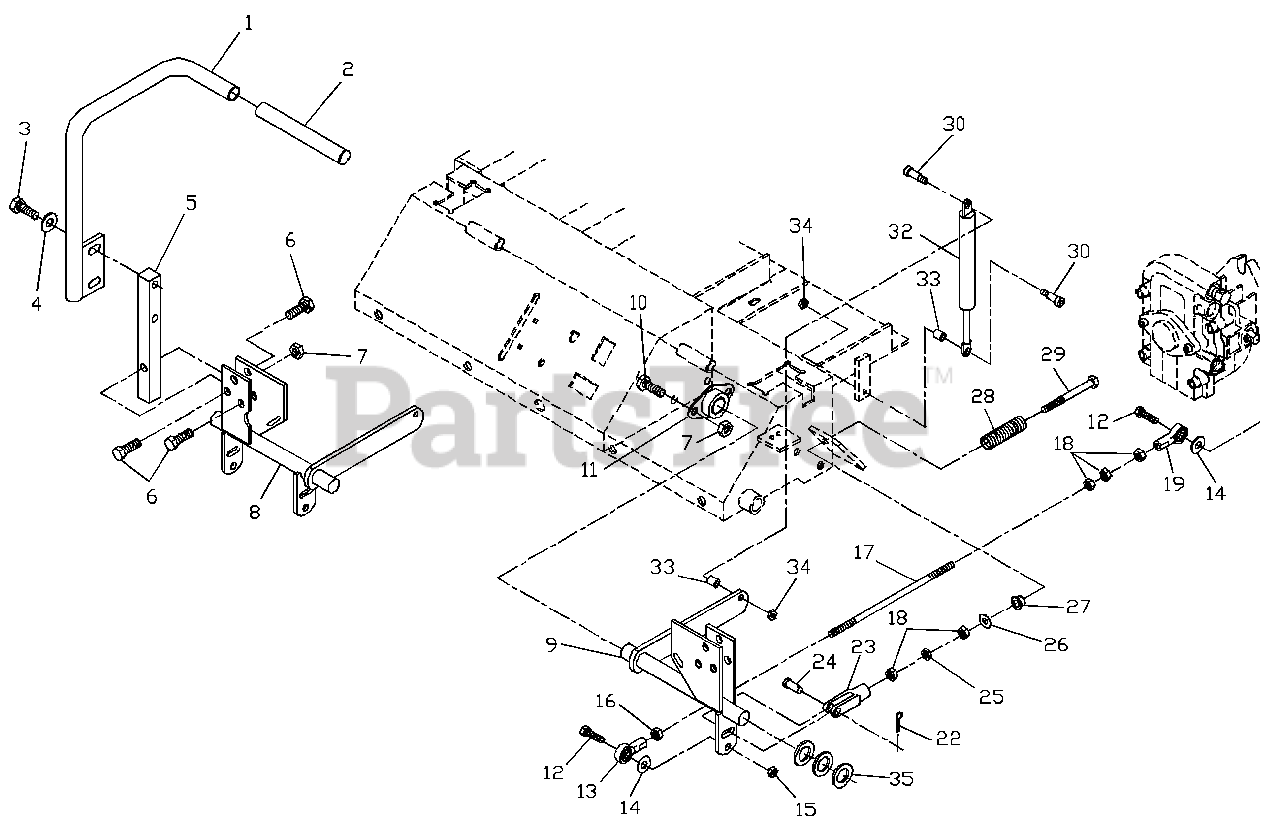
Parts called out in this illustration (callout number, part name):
1	MOTION CONTROL HANDLE, RIGHT
3	3/8C X 1 HEX CAP SCREW
4	3/8 DISC SPRING WASHER
5	CONTROL ARM
6	3/8C X 1 3/4 HEX CAP SCREW
7	3/8C CENTERLOCK NUT
8	BRACKET, RIGHT
9	BRACKET, LEFT
10	3/8C X 3/4 HEX CAP SCREW
11	FLANGE BEARING
12	5/16C X 1 1/4 HEX CAP SCREW
13	BALL JOINT, LEFT HAND THREAD
14	5/16 FLAT WASHER
15	5/16C CENTERLOCK NUT
16	5/16F JAM NUT, LEFT HAND THREAD
17	PUMP CONTROL LINK
18	5/16F HEX NUT
19	BALL JOINT, RIGHT-HAND THREAD
20	PUMP CONTROL ARM
21	5/16C X 5/8 SQ HEAD SET SCREW
22	3/32 X 1/2 COTTER PIN
23	5/16F YOKE
24	5/16 X 1 CLEVIS PIN
25	5/16F HEX JAM NUT
26	1/4 FLAT WASHER
27	NYLON BUSHING
28	NEUTRAL DETENT SPRING
29	SHOULDER SCREW, NEUTRAL RETURN
30	5/16 X 5/8 SHOULDER SCREW
34	1/4C CENTERLOCK NUT
35	MACH BUSHING
